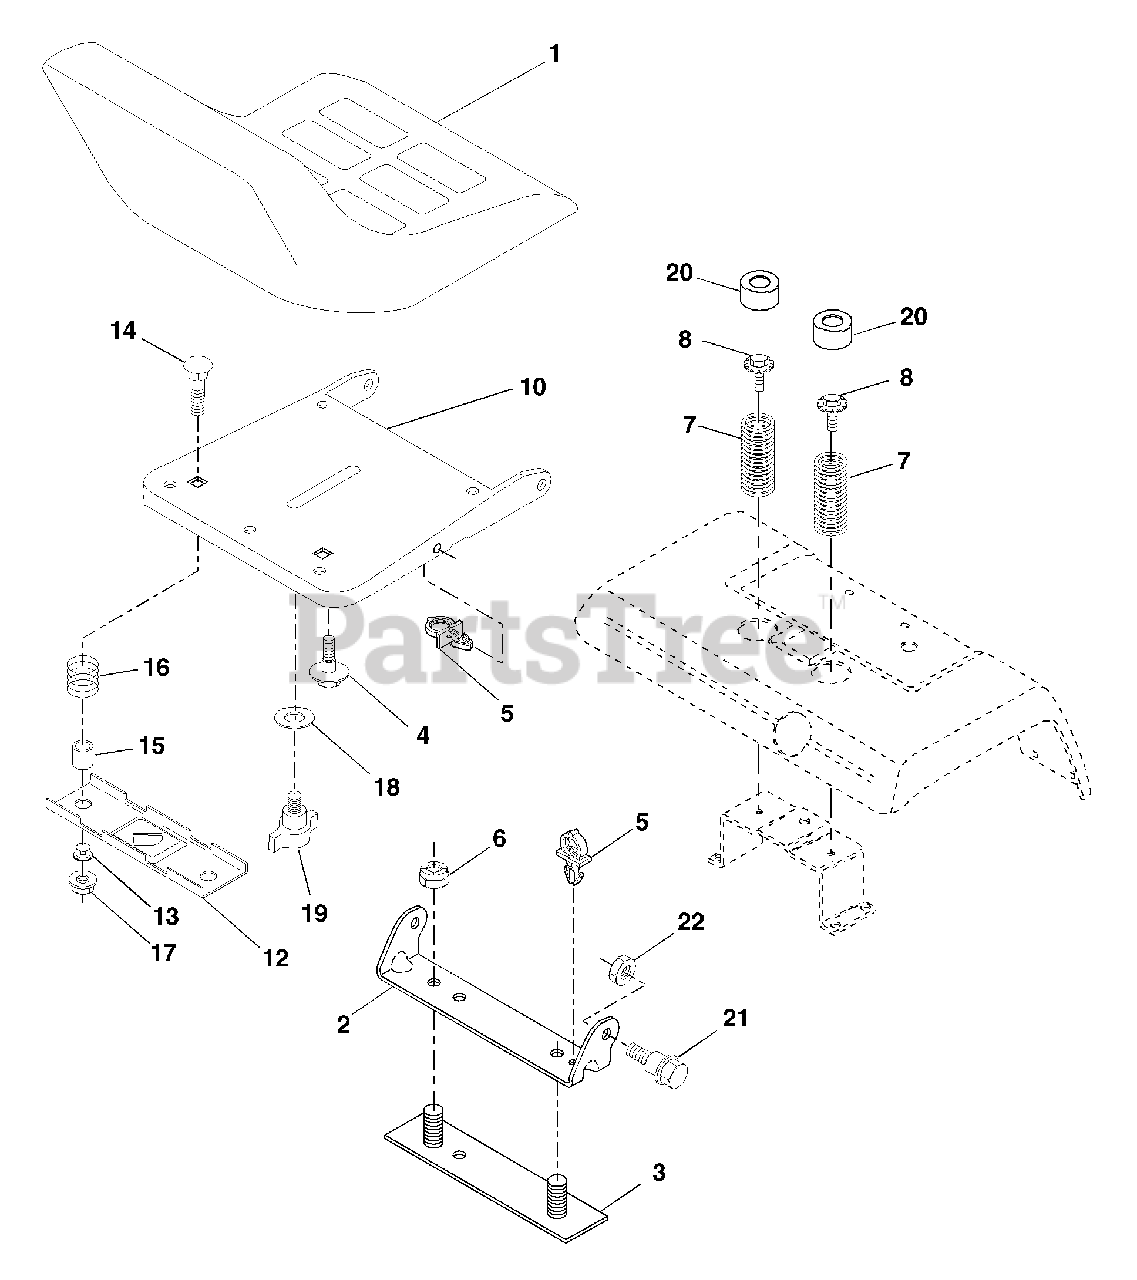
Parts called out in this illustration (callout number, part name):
1	Seat
2	Bracket, Pivot Seat
3	Strap, Fender Asm.
4	Bolt, Shoulder 5/16-18 x .62
5	Clip, Push-In Hinged
6	Nut, Crownlock 3/8-16
7	Spring, Seat Cprsn.
8	Bolt 5/16-18 UNC x 3/4 w/Sems
10	Pan, Seat
12	Bracket, Mounting Switch
13	Bushing, Snap
14	Bolt, Carriage 1/4-20 x 1-1/2
15	Spacer, Split
16	Spring, Cprsn.
17	Nut, Lock 1/4 Lg. Flg. Gr. 5
18	Washer 17/32 x 1-3/16 x 12 Ga.
19	Knob, Seat
20	Cap, Spring Seat Blk
21	Bolt 5/16-18 Unc-2A
22	Nut, Crownlock 5/16-18
